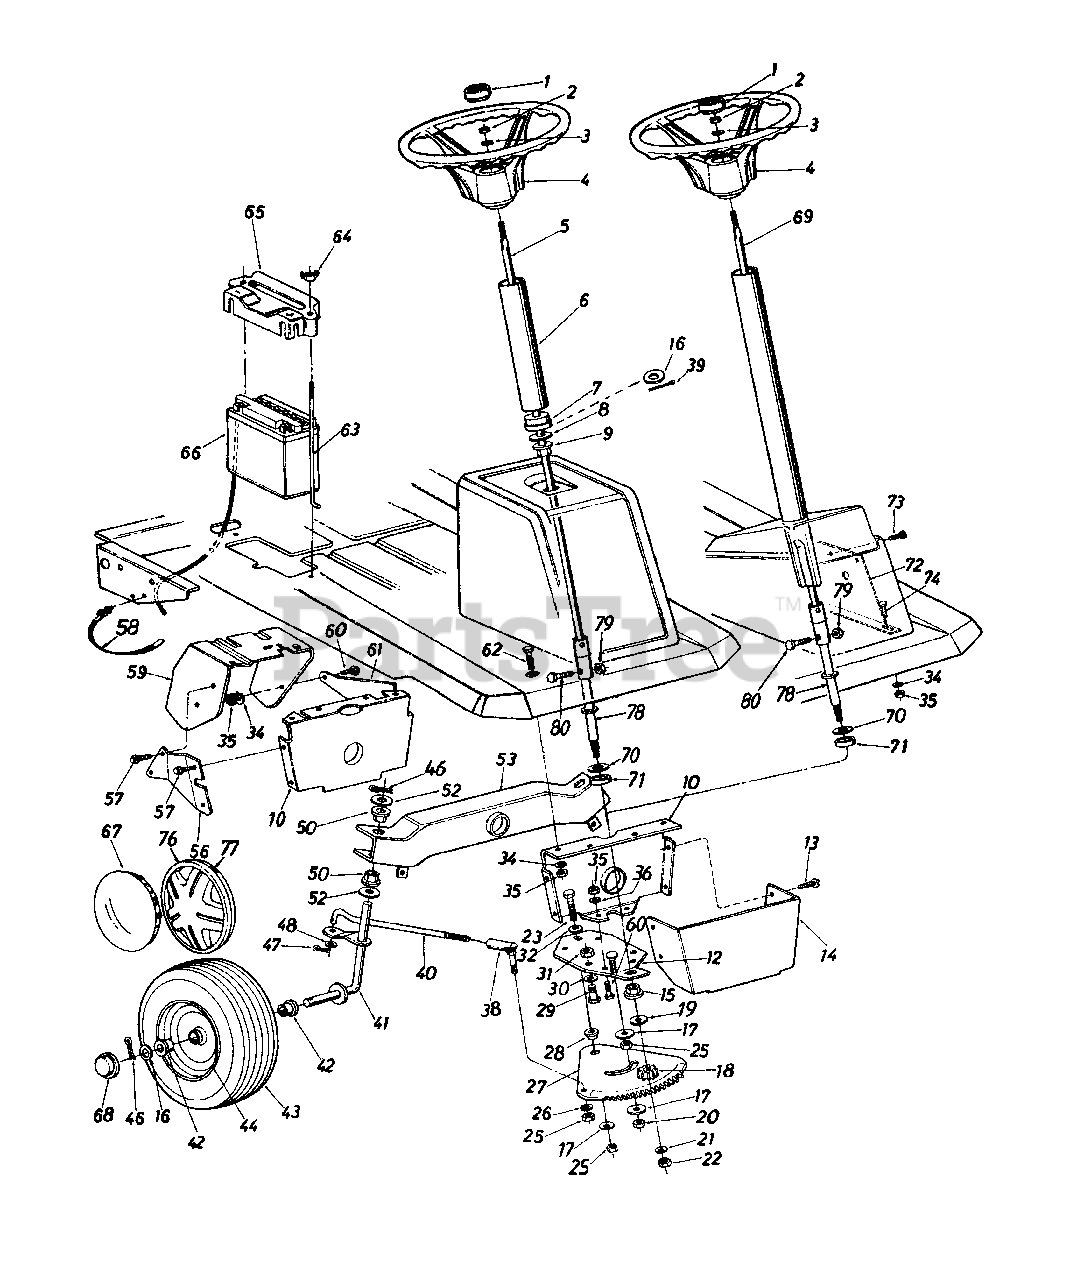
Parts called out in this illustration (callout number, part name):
1	Steering Wheel Cap
2	Hex L-Nut 5/16-24 Thd.
3	Bell-Wash. .345" I.D. x .88" O.D.
4	Steering Wheel Ass'y. (3 Spoke)
5	Steering Shaft Ass'y.
8	Fl-Wash. .635" I.D. x 1.24" O.D,
9	Hex Flange Bearing
13	Hex Wash. Hd. AB-Tap Scr. 1/4 x .62" L
16	Fl-Wash. .640" I.D. x 1.5" O.D.
17	Fl-Washer 3/8" I.D. x 1.37" O.D.
18	Steering Pinion Gear
19	Fl-Wash. .510" I.D. x 1" O.D.
20	Hex L-Nut 3/8-24
21	Fl-Wash. .34" I.D. x .68" O.D.
22	Hex Nut 5/16-24 Thd.
23	Hex Bolt 3/8-24 x 1.5" Lg. (Grade 5)
25	Hex Nut 3/8-24 Thd.
26	L-Wash. 3/8" I.D.
27	Steering Gear Segment
28	Shoulder Spacer .622" Dia. x .218
29	Hex Bolt (Nylon) 1/2-13 x .75"
30	Fl-Wash. .530" I.D. x .930"
31	Hex Nut 1/2-13 Thd.
32	Bell-Wash. .385" I.D. x .88"
34	L-Wash, 5/16" I.D.
35	Hex Nut 5/16-18 Thd.
36	Spr. Wash. .32" I.D. x .62" O.D.
38	Ball Joint Ass'y. 3/8-24 Thd.
39	Cotter Pin 1/8" Dia. x 1.00" Lg.
40	Steering Tie Rod
41	Front Axle Ass'y.-R.H.
42	Flange Bearing
43	Front Wheel Ass'y. Comp.
44	Front Wheel Rim Only
46	Cotter Pin 1/8" Dia. x 1.25"
47	Cotter Pin 1/8" Dia. x 1.00"
48	Fl-Wash. .385" I.D. x .87"
50	Hex Flange Bearing
52	Fl-Wash. .635" I.D. x 1.12"
58	Cable Tie
59	Clutch-Brake Pedal Ass'y.
60	Hex Bolt 5/16-18 x .75" Lg.
63	Battery Hold Down Rod
64	Wing Nut Solid 1/4-20 Thd.
65	Battery Hold Down Cover
66	12V Battery
67	Chrome Hub Cap
68	Plastic Hub Cap
69	Steering Shaft Ass'y.
70	Fl-Wash. .635" I.D. x 1.24" O.D.
71	Spacer (Plastic)
74	Hex Bolt 5/16-18 x 2.00" Lg.
76	Hub Cap-Beige
77	Spring Clip
78	Steering End Adapter
79	Hex Nylon L-Nut 1/4-20 Thd.
80	Hex Bolt 1/4-20 x 1.31" Lg.
